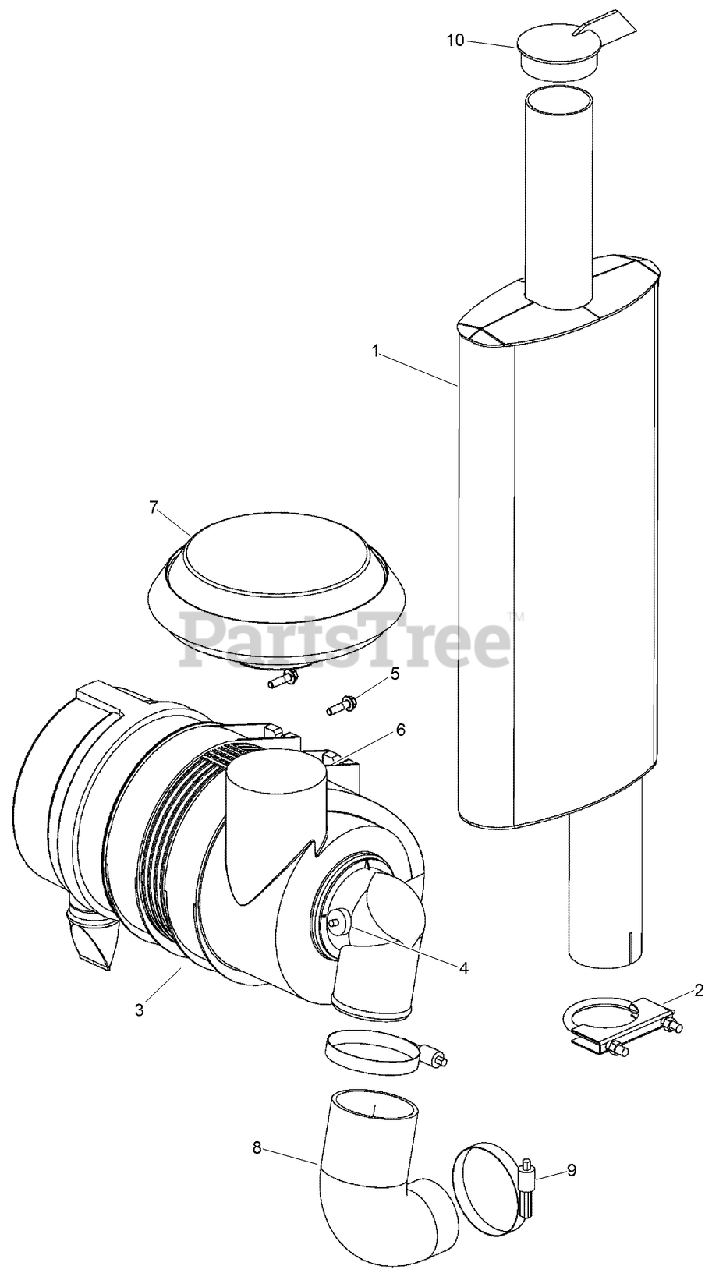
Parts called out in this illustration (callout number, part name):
1	MUFFLER - Exhaust
2	BOLT-U, CLAMP
3	ASM-Air Cleaner
4	MOUNT-Air Cleaner
5	SCREW, METRIC FLANGE FULL - M8 x 25
6	NUT-TORQUE, PREVAILING
7	COVER - Rain Cap, Air Cleaner
8	HOSE - Intake
9	CLAMP-TORQUE, CONSTANT
10	CAP-RAIN
